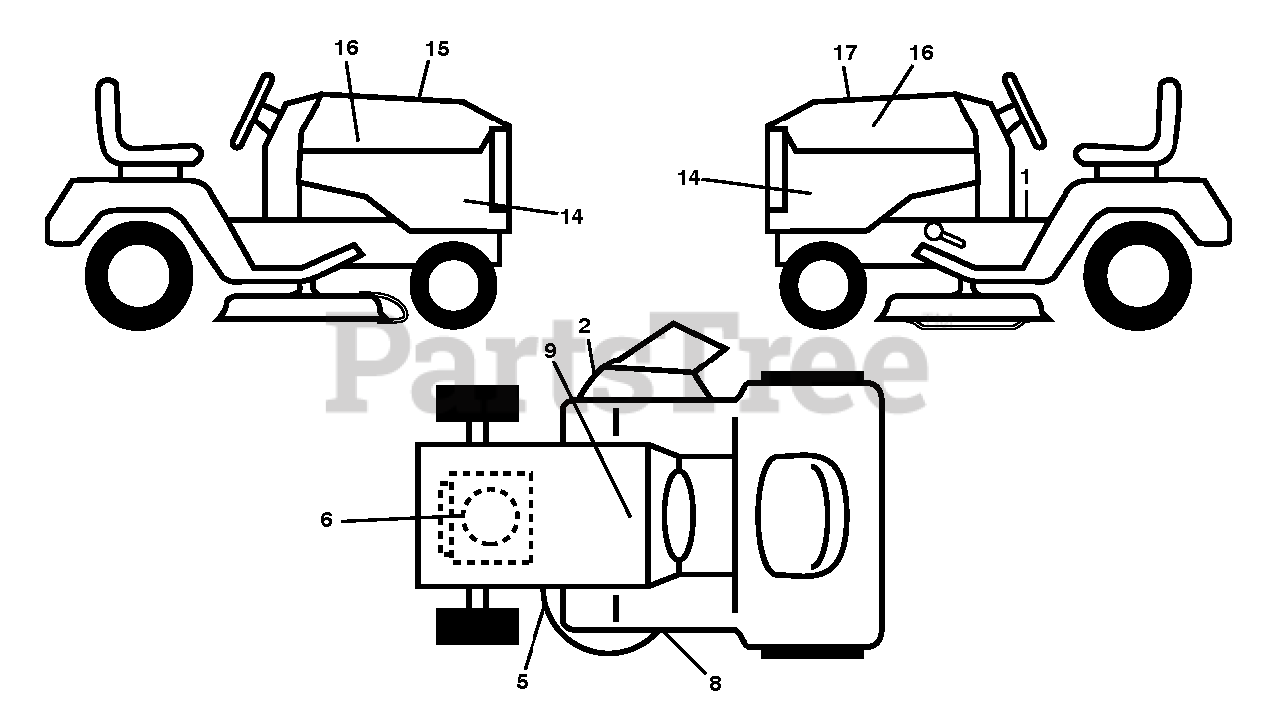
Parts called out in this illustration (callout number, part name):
1	DECAL.FENDER.WARNING.ENG
2	DECAL.WARN.KEEP.HAND.AWAY
5	DECAL.MOWER
6	Decal, Engine Hp
8	DECAL.MOWER.SCH.48/54
9	DECAL BTRY SYMBOLS
14	DECAL.SIDE PANEL.YTH23V48
15	DECAL.WARNING.CUST.RESP.E85.
16	RP.DECAL.BADGE.170MM.TEXTLOGO
17	Decal, Replacement BSM44
